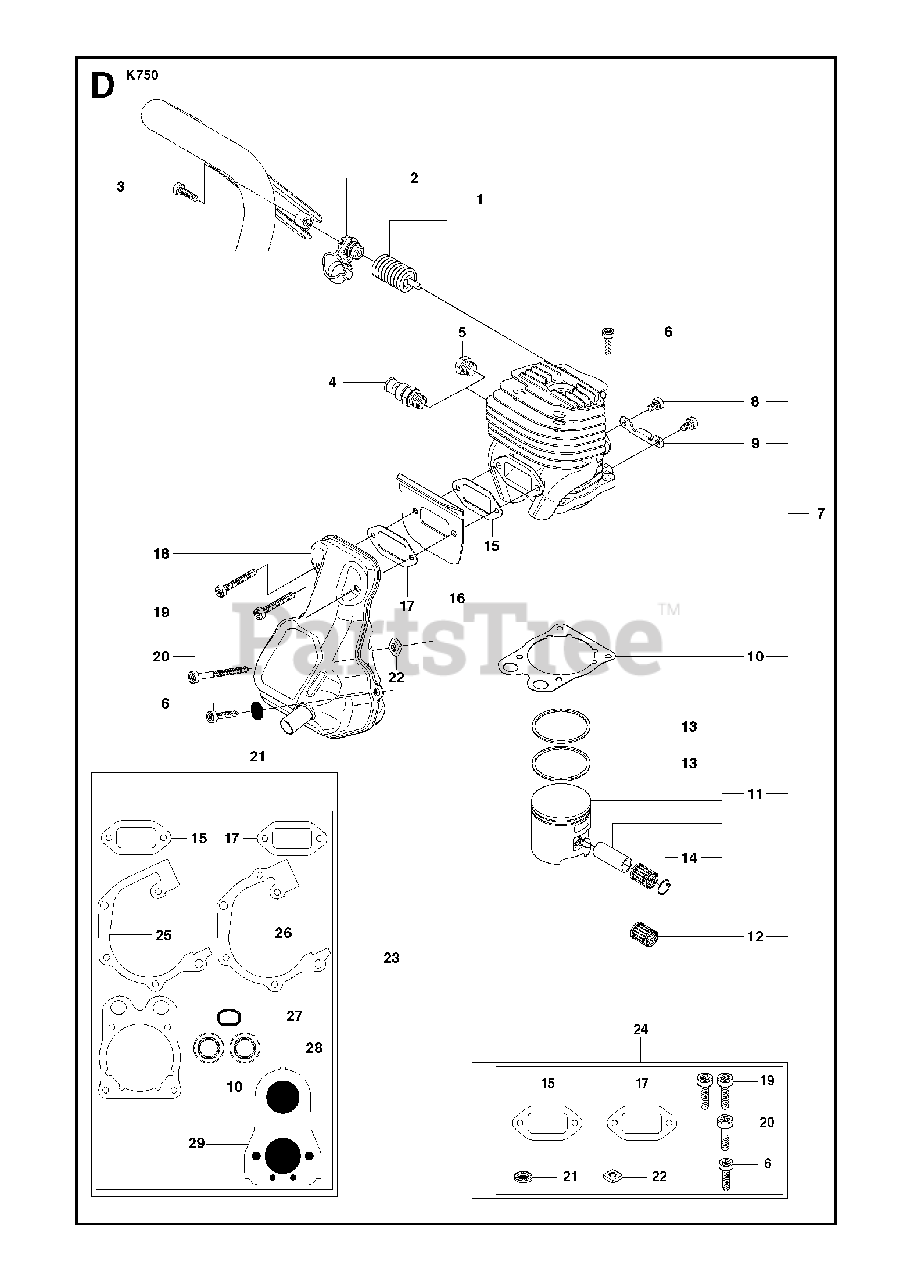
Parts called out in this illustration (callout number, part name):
1	ANTIVIBRATION ELEMENTIncl. 2
2	SPRING HOLDER
3	SCREW ITXSCM
4	DECOMPRESSION VALVE
6	SCREW ITXSCM
7	CYLINDER ASSYIncl. 8 - 12
8	SCREW ITXSCM
11	PISTON ASSYIncl. 13 - 14
12	NEEDLE BEARING
13	PISTON RING
16	COOLING AIR CONDUCTOR
17	GASKET
18	MUFFLER ASSY
19	SCREW ITXSCM
20	SCREW ITXSCM
23	GASKET KITIncl. 10, 15, 17, 25 - 29
24	MUFFLER KITIncl. 6, 15, 17, 19 - 22
28	SEALING RING
29	GASKET
